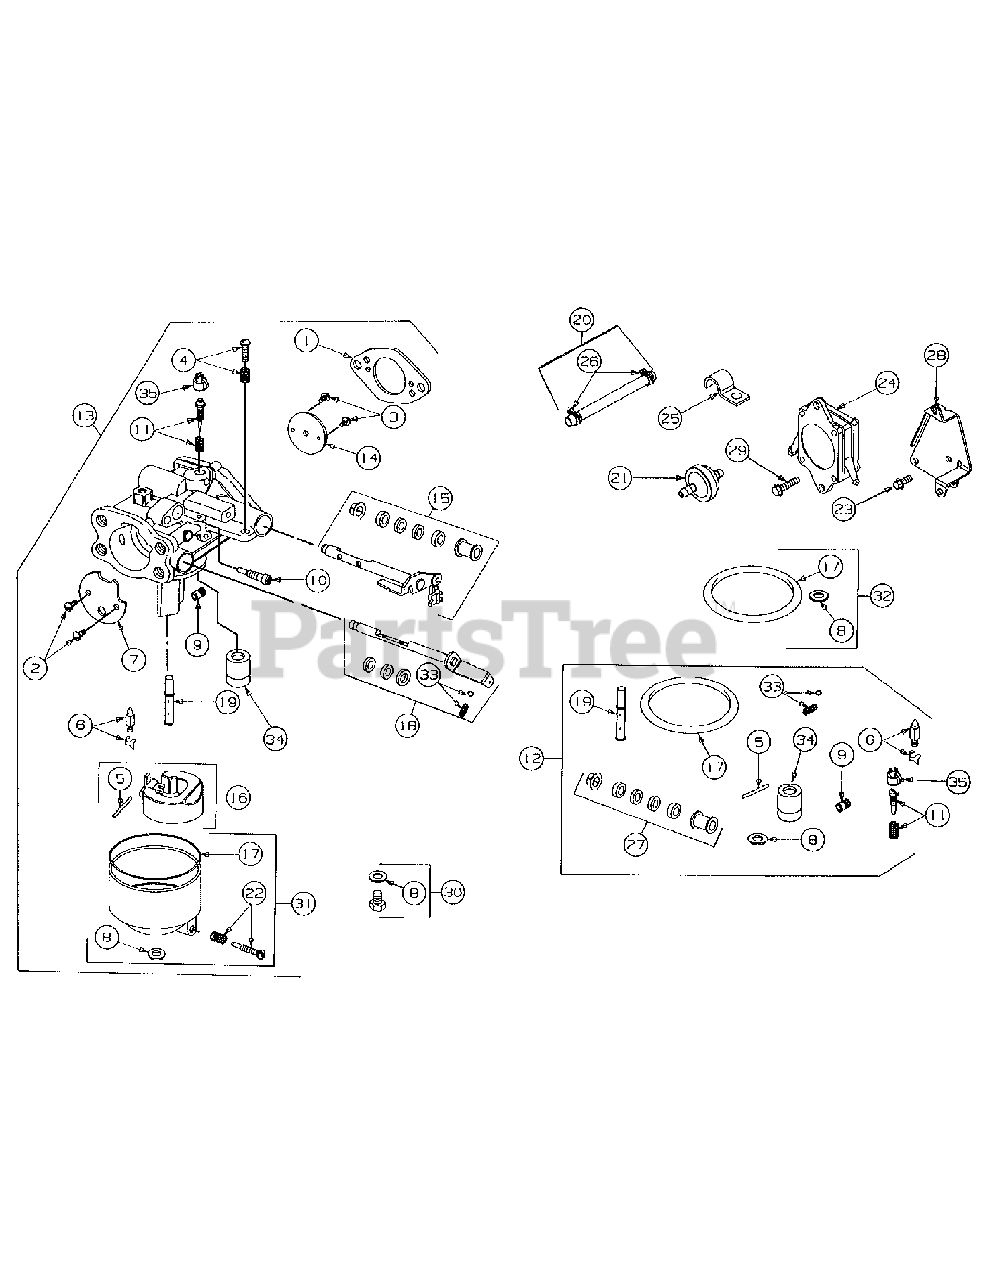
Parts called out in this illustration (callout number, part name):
1	Gasket, Carburetor Mtg
2	Screw, Valve
3	Screw, Valve
4	Screw, Throttle Adjustment
5	Pin, Float Hinge
6	Valve, Fuel Inlet
7	Vavle, Choke
8	Washer, Bowl
10	Jet, Pilot
11	Valve, Idle Adjusment Needle
12	Carburetor Overhaul Kit
13	Carburetor Assembly
14	Valve, Throttle
15	Shaft Assembly, Throttle
16	Float, Bowl
17	Gasket, Bowl
18	Shaft, Choke
19	Nozzle, Carburetor
20	Hose, Fuel 11'
20	Hose, Fuel 23''
21	Filter, Fuel
22	Drain, Carbureto Bowl
23	Screw, Sem
24	Pump, Fuel
25	Clamp, Fuel Pipe
26	Clamp, Hose
27	Seal Kit, Shaft
28	Bracket, Fuel Pump
29	Screw, Mtg
30	Screw, Fuel Bowl
31	Bowl Assembly, Fuel
32	Gasket Set, Carburetor
33	Ball, Choke Locator
34	Inlet, Fuel
35	Cap, Limiter
